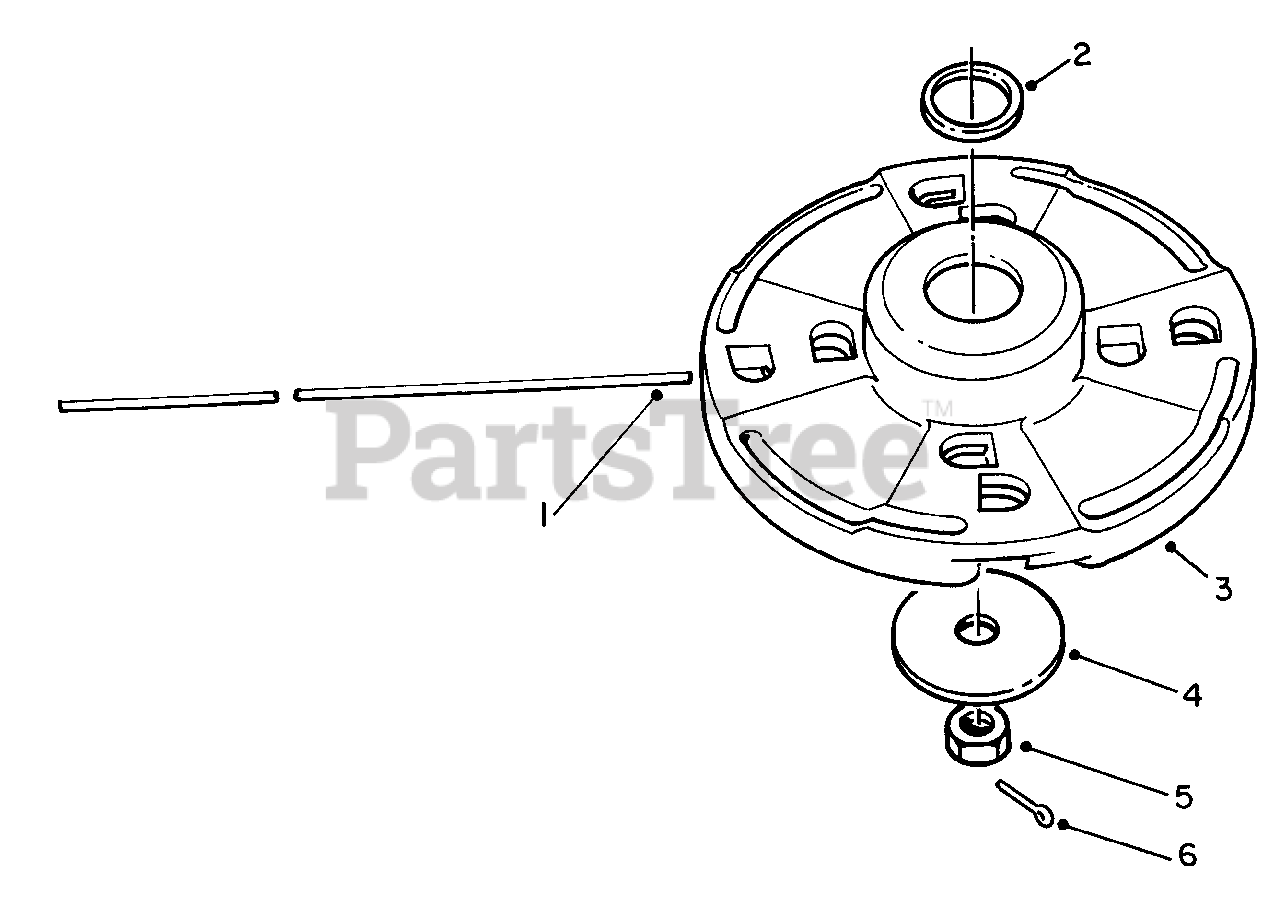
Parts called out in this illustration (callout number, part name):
1	.105 (100 Pcs. ) (Optional)
2	Spacer
3	Head Assembly (Incl. Ref. #2)
4	Washer-Plate
6	Cotter Pin
